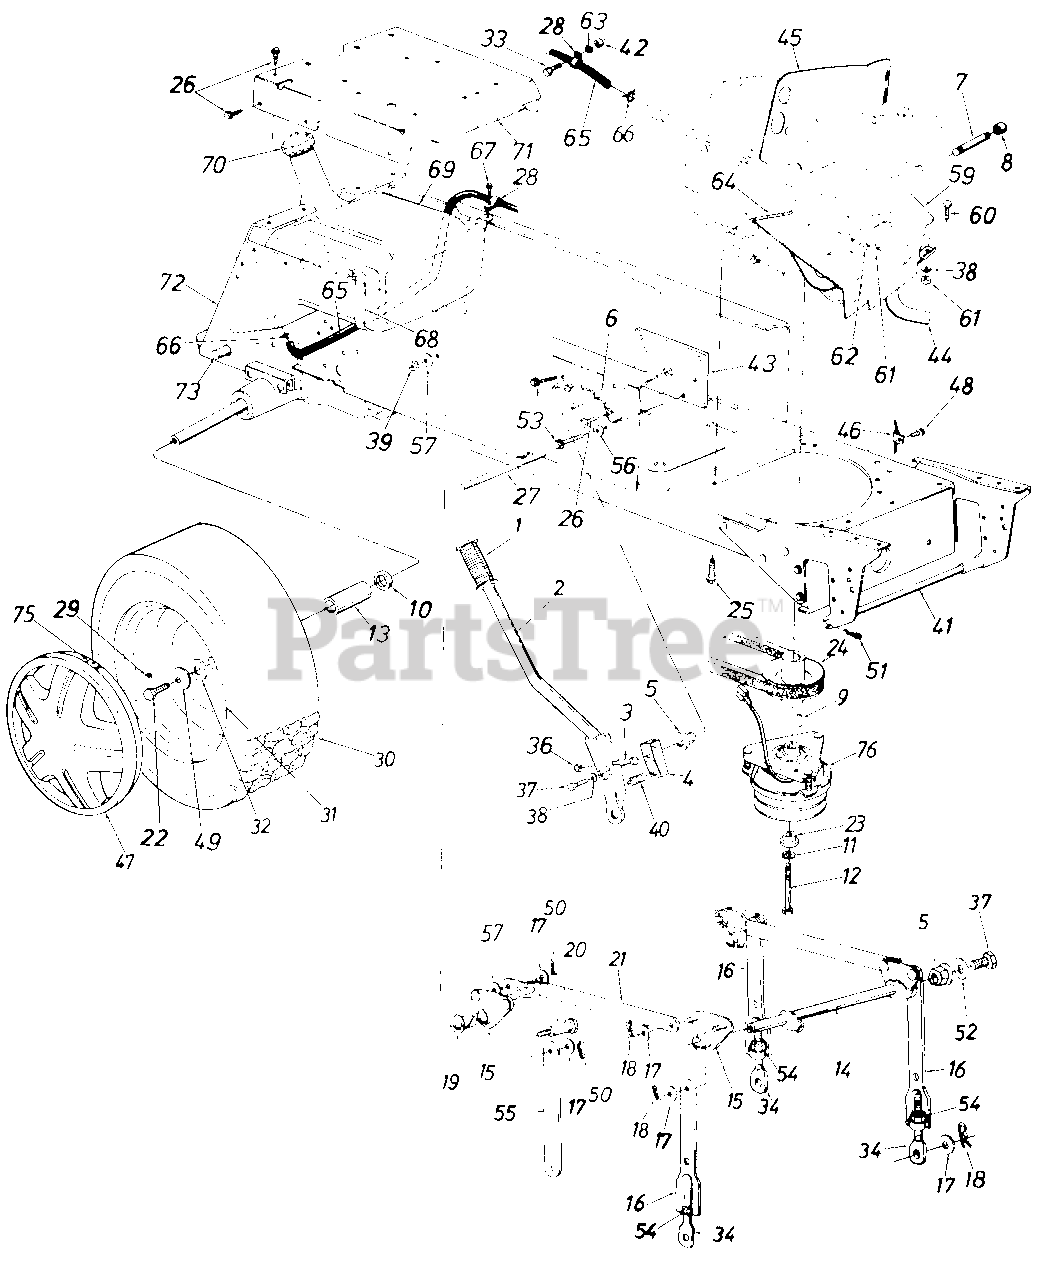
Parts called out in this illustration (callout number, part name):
1	Grip
2	Lift Handle Ass'y.
3	Hex Bolt 5/16-18 x 1.5" Lg.
4	Lift Shaft Drive
5	Plastic Hex Brg. 5/8" I.D.
8	Pipe Cap 3/8-18 Npt.
9	Sq. Key 1/4" x 1/4" x 1.50" Lg.
10	Fl-Wash. .76" I.D. x 1.49" O.D.
11	L-Wash. 7/16" I.D.
12	Hex Bolt 7/16-20 x 3.75" Lg.
13	Sleeve 75" I.D. x 1.0" O.D.
14	Lift Shaft Ass'y.
15	Lift Pivot Brkt. Ass'y.
17	Fl-Wash. 1/2" I.D. x 1.00" O.D. x .090"
18	Hairpin Cotter
19	Nyliner 5/8" I.D. x .88" Lg.
20	Shld. Bolt 5/8" Dia. x .96" Lg. 3/8-16
23	Shoulder Spacer
24	Engine Pulley
25	Hex Wash. Hd. Scr. 3/8-16 x 1.25" Lg.
26	Hex Thd. Rolling Scr. 5/16-18 x.75" Lg.
27	Running Board Rod
28	Clamp
29	Air Valve
32	Flat Washer .34" I.D.
33	Hex Bolt 1/4-20 x .62" Lg.
34	Eye Bolt Adj. Link 1/2-13 Thd.
36	Hex Cent. L-Nut 5/16-18 Thd.
37	Hex Bolt 5/16-24 x .62" Lg.
38	L-Wash. 5/16" I.D.
39	Hex Top L-Nut 3/8-16 Thd.
40	Compression Spring
41	Deck Connecting Rod
42	Hex Nut 1/4-20 Thd.
45	Heat Shield
46	Mounting Clamp
47	Hubcap
48	Hex Wash. Hd. TT-Tap Scr. 1/4-20 x .5" Lg.
49	Bell-Wash. .39" I.D.
50	Cotter Pin .09 Dia. x 1.0" Lg.
51	Int. Cotter Pin
52	Flat Wash. .34" I.D. x 1.12" O.D. x .125"
53	Hex Wash. Hd. AB-Tap Scr. 5/16-24 x .5" Lg.
54	Hex Nut 1/2-13 Thd.
56	Fl-Wash..344" I.D.
57	Bell-Wash. .4" I.D. x 1.13" O.D.
59	Front Heat Shield
60	Hex Bolt 5/16-18 x .75" Lg.
61	Hex Nut 5/16-18 Thd.
62	L-Wash. 5/16" I.D.
63	L-Wash. 1/4" I.D.
64	Trim Strip 10" Lg.
65	Fuel Line 50" Lg.
66	Hose Clamp
67	Hex AB-Tap Scr. 1/4 x .62" Lg.
68	Fuel Tank Strap
69	Gas Tank
70	Gas Gauge
71	Seat Plate
75	Spring Clip
76	Electric Clutch
